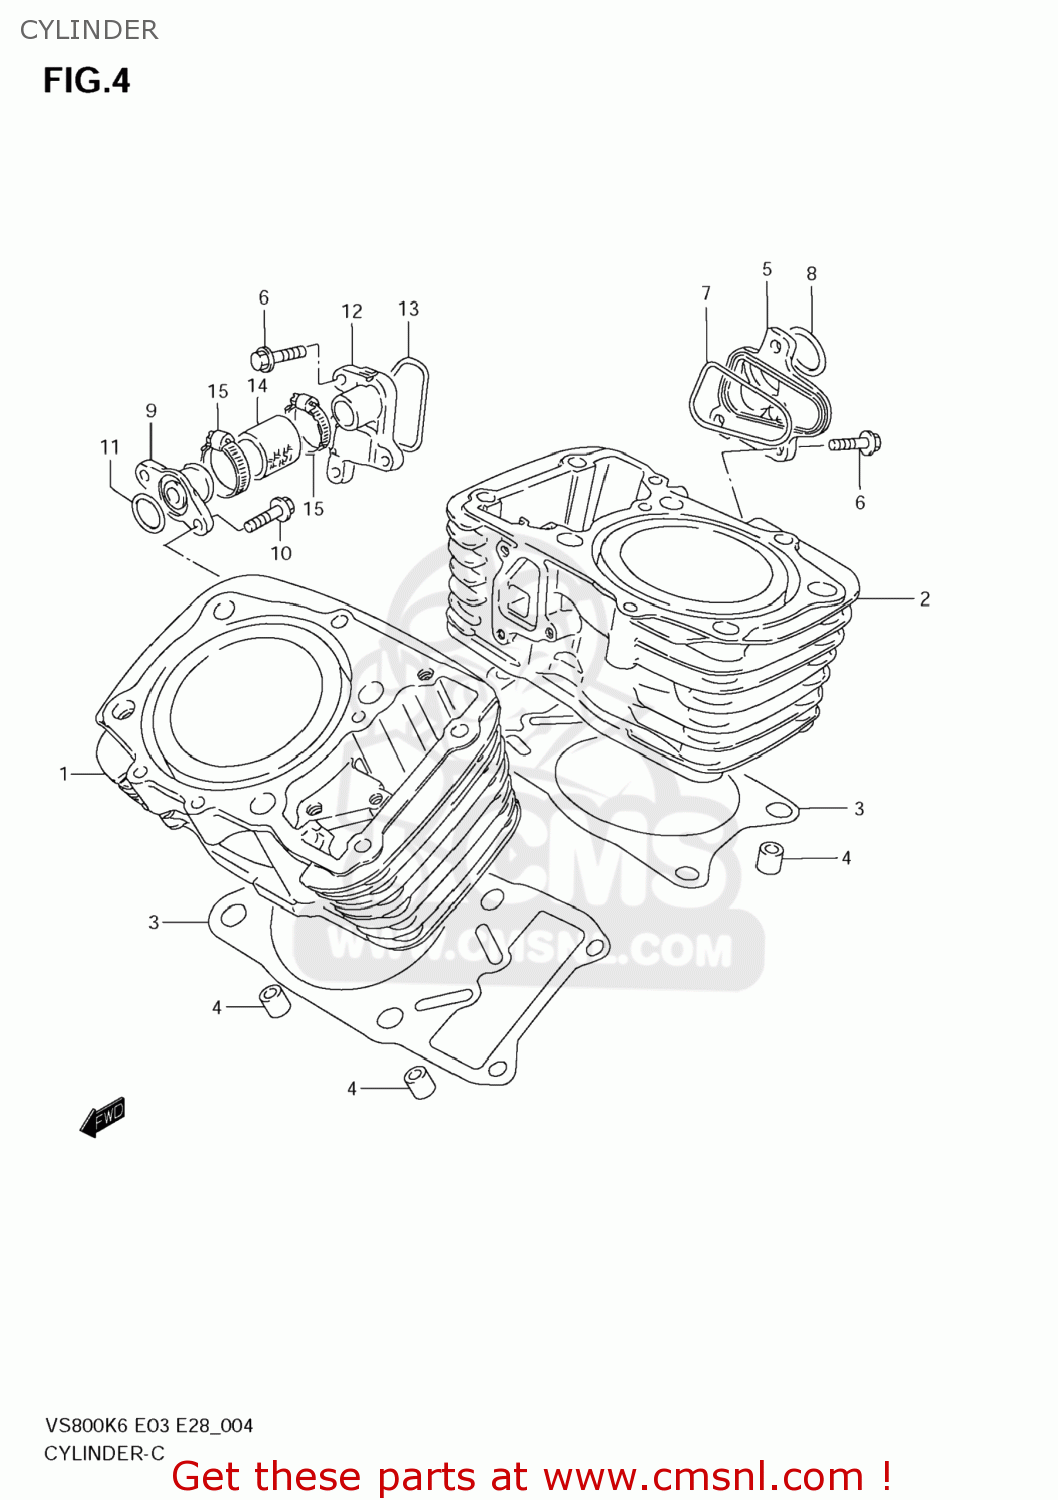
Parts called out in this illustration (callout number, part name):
1	CYLINDER,FR
2	CYLINDER,RR
3	GASKET,CYLINDER (NAS)
4	PIN
5	CONNECTOR,CYLINDER INLET PIPE
6	BOLT
7	O RING,INLET WATER CHAMBER
8	O RING(D:2.3,ID:24.4)
9	UNION,CYL INLET
10	BOLT
11	O RING(D:2.4,ID:15.8)
12	CHAMBER,WATER OUTLET
13	O RING,OUTLET WATER CHAMBER
14	HOSE,RADIATOR INLET
15	CLAMP
